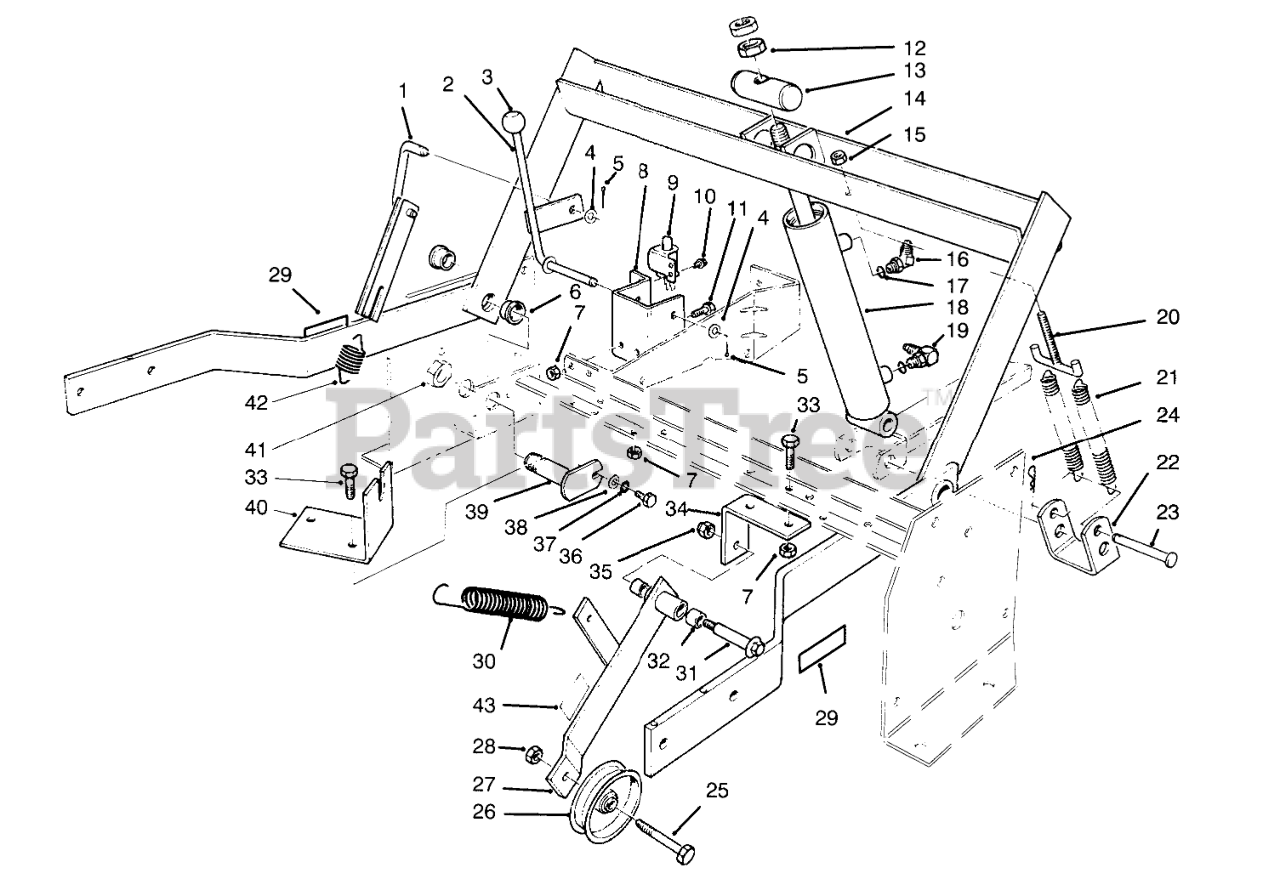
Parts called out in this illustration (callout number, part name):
1	Link-Parking Brake
2	Brake Lever
4	WASHER-FLAT
5	PIN-COTTER
6	BEARING-FLANGE
7	NUT-LOCK, NI
8	Bracket-Parking Brake
9	SWITCH-BRAKE, PARKING
10	SCREW-TAPTITE
11	SCREW-HH
12	NUT-JAM
13	CYL.PIVOT PIN
14	Frame-Lift(Incl Ref. #6)
15	NUT-HEX, SIDE DEFORM
16	FITTING-45 DEG
17	O-RING
18	CYLINDER - LIFT
19	FITTING-ELBOW, 90
20	T-HOOK W A
21	SPRING_EXTENSION
22	SPRING BRACKET
23	PIN-CLEVIS
24	PIN-HAIR
25	SCREW-HH
26	PULLEY-IDLER
27	Lever-Idler(Incl Ref. #43)
28	NUT-LOCK, NI
29	WARNING DECAL
30	IDLER EXT SPRING
31	BOLT-WHEEL
32	BUSHING
33	SCREW-HH
34	JACKSHFT IDLR BRKT
35	NUT-LOCK
36	SCREW-HH
37	WASHER-LOCK
38	WASHER-FLAT
39	Pin-Pivat
40	TRACT CABLE BRKT
41	NUT-LOCK, NI
42	PARK BRAKE SPRING
43	DECAL-WARNING
